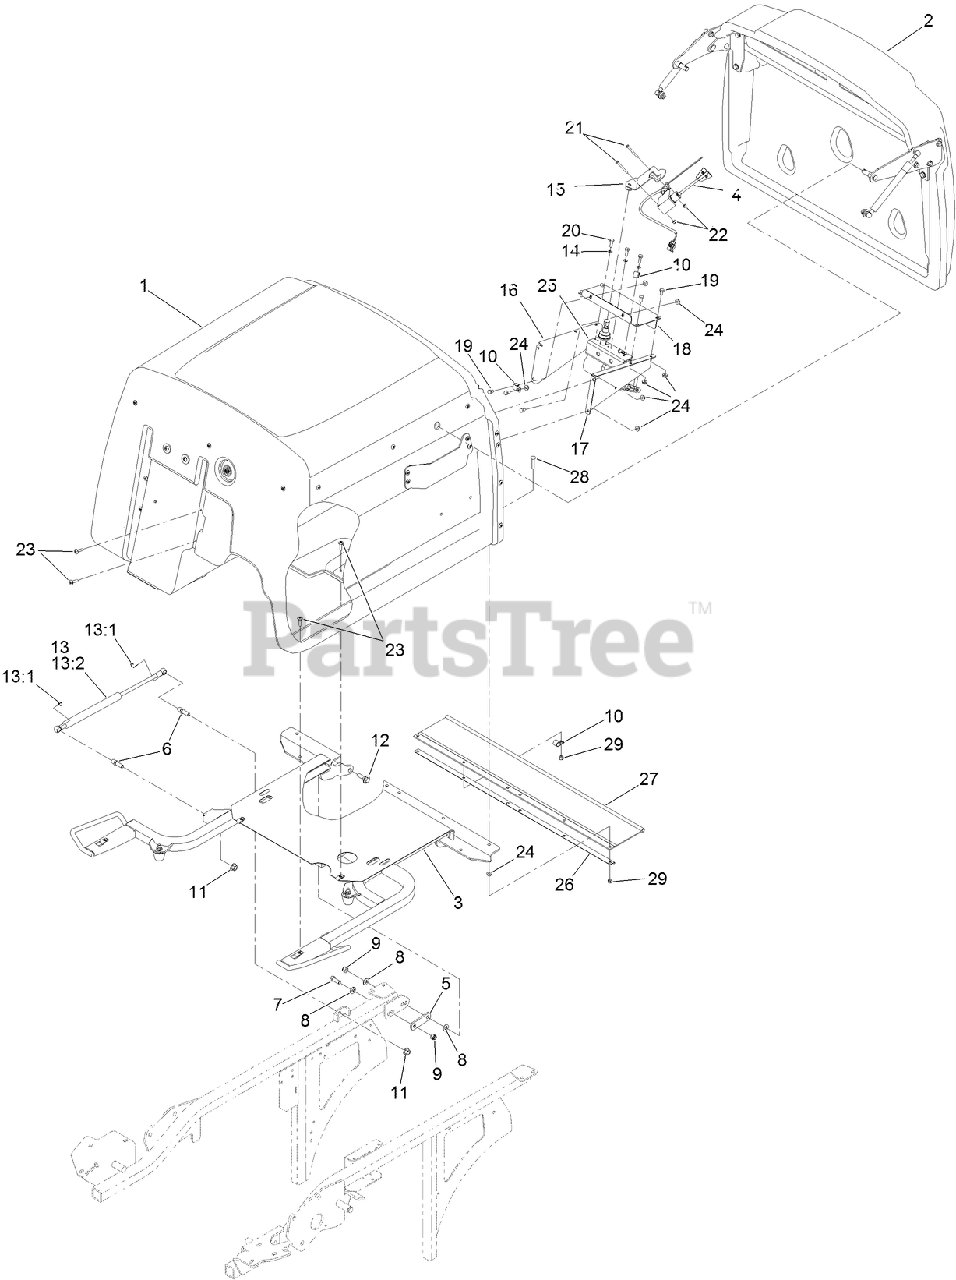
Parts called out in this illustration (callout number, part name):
1	HOPPER ASM
2	HOPPER DOOR ASM
3	HOPPER FRAME ASM
4	FILL SENSOR ASM
5	ARM-LIFT, DECK
6	STUD-BALL
7	SCREW-HH
8	WASHER-FLAT
9	NUT-LOCK, NI
10	CLIP-LOOM
11	NUT-HF
12	SCREW-SHOULDER, HWH
13	DAMPER KIT
13:1	CLIP-RETAINER
13:2	SHOCK-COMPRESSION, GAS
14	WASHER-SPRING
15	MOUNT-SWITCH
16	BRACKET-DRIVE MOTOR, LH
17	BRACKET-DRIVE MOTOR, RH
18	PLATE-SWITCH
19	SCREW-HH
20	SCREW-HH
21	SCREW-PPH
22	NUT-LOCK, NI
23	SCREW-TTH
24	NUT-HF
25	MOTOR WIRING ASM
26	CHANNEL-FRAME, HOPPER
27	DEFLECTOR-GRASS
28	SCREW-CARR
29	NUT-LOCK, NI
